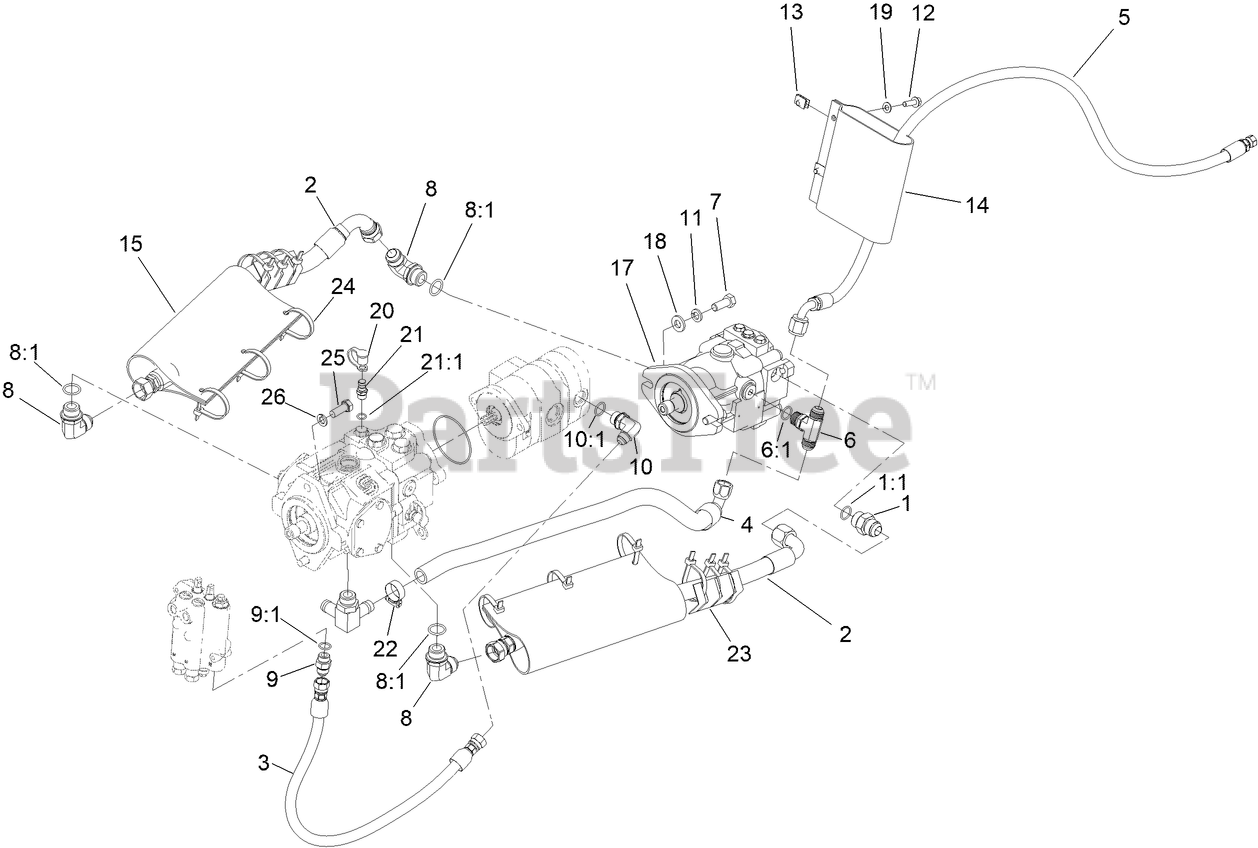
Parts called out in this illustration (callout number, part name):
1	FITTING-STRAIGHT
1:1	O-RING
2	HOSE (PUMP TO REG VALVE)
3	HOSE ASM
4	HOSE-ASM
5	HOSE-ASM
6	FTTG-TEE
6:1	O-RING
7	SCREW-HH
8	FITTING-ELBOW, 90 DEG
8:1	O-RING
9	FITTING-STRAIGHT
9:1	O-RING
10	FITTING-90 DEG
10:1	O-RING
11	WASHER-LOCK
12	SCREW-HHF
13	NUT-CLIP, U
14	BOOT-HOSE
15	BOOT-HOSE
17	HYD PISTON MOTOR ASM
19	WASHER-PLAIN
20	CAP-DUST
21	FITTING-DIAGNOSTIC
21:1	O-RING
22	CLAMP-HOSE
23	PROTECTOR-HOSE
24	TIE-CABLE
25	SCREW-HH
26	WASHER-LOCK
